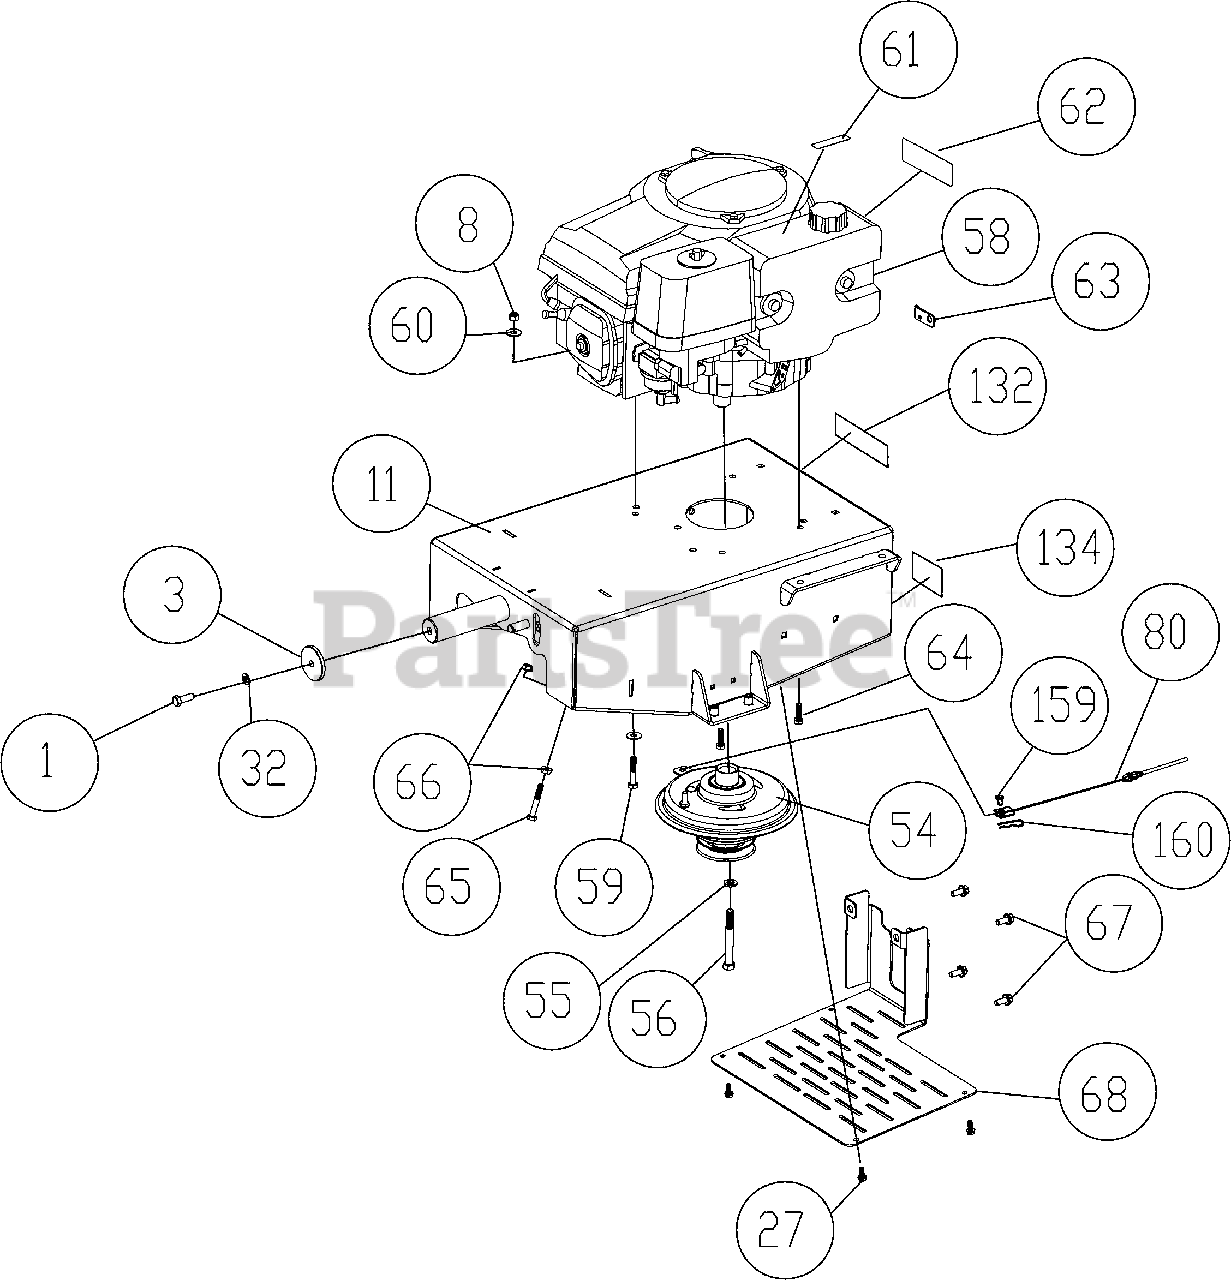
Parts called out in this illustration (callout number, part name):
1	SCREWCAP 3/8-24 X 1” HCS GR. 8
3	WASHER DECK RETAINING
8	NUT LOCK 5/16”-18 ZP
11	ENGINE BASE WA W/LABELS
27	SCREW SELT TAP 1/4-20 X 5/8” HWH TYPE F
32	WASHER LOCK 3/8” S/T MED
54	CLUTCH
55	WASHER LOCK S/T MED
56	SCREWCAP 7/16”-20 X 3 1/2” GR 8 W/PATCH
58	ENGINE HONDA
59	SCREWCAP 5/16”-18 X 1 3/4 HCS ZP
60	WASHER 5/16” FLAT
61	LABEL WARNING FUEL
62	LABEL SPARK ARRESTOR
63	PLATE CHOKE BC26
64	SCREWCAP 5/16-24 X 1” GR 8 ZP W/PATCH
65	SCREWCAP 5/16”-18 X 2” HCS ZP
66	NUT FLANGE 5/16”-18 ZP
67	SCREW SER HEX WSHR FLNG 5/16-18 X 3/4”
68	GUARD REAR HYDRO BC26
80	CABLE CLUTCH
132	LABEL MADE IN USA
134	LABEL SAFETY PROTECT READ MANUAL
159	PIN CLEVIS 0.25 X 0.050
160	PIN HITCH CLIP 0.051 X 3/4
